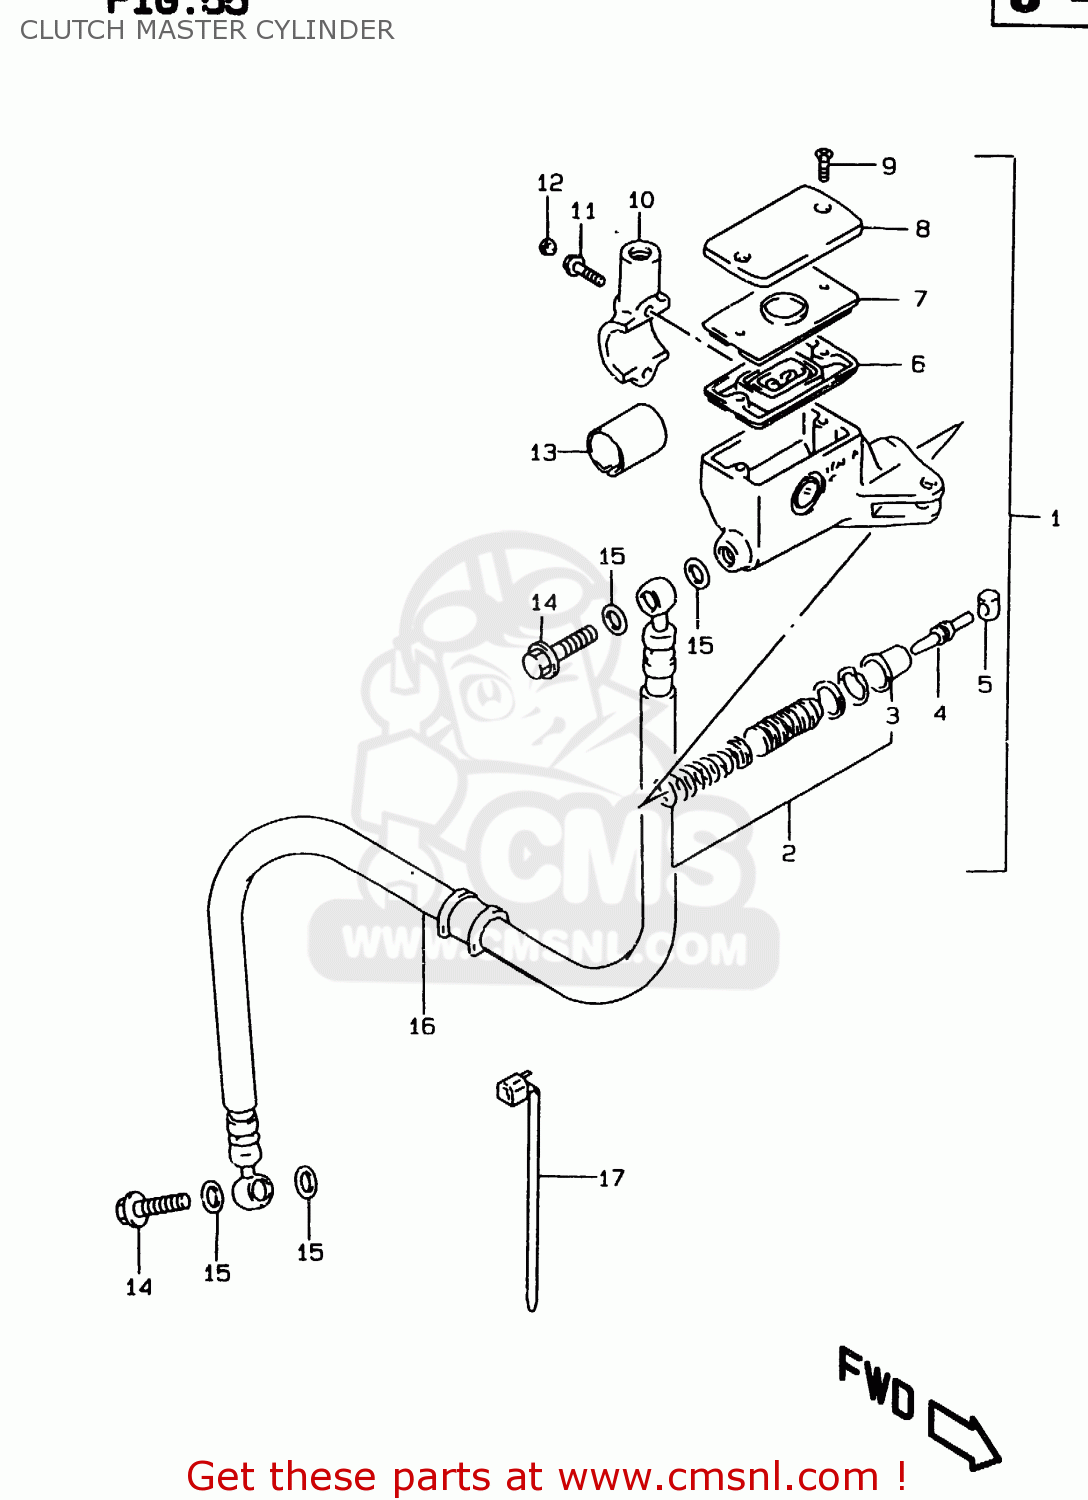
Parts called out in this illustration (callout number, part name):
1	CYLINDER ASSEMBLY,CLUTCH MASTER
2	PISTON & CUP SET
3	BOOT
4	PUSH ROD
5	BUSH
6	7
7	PLATE,DIAPHRAGM
8	CAP
9	SCREW
10	HOLDER
11	BOLT,CRKCASE,R
12	CAP(OD:10)
13	SPACER,CLUTCH MASTER CYLINDER
14	BOLT UNION
15	WASHER(10X15X1.5)
16	HOSE,CLUTCH
17	CLAMP(L:125)
